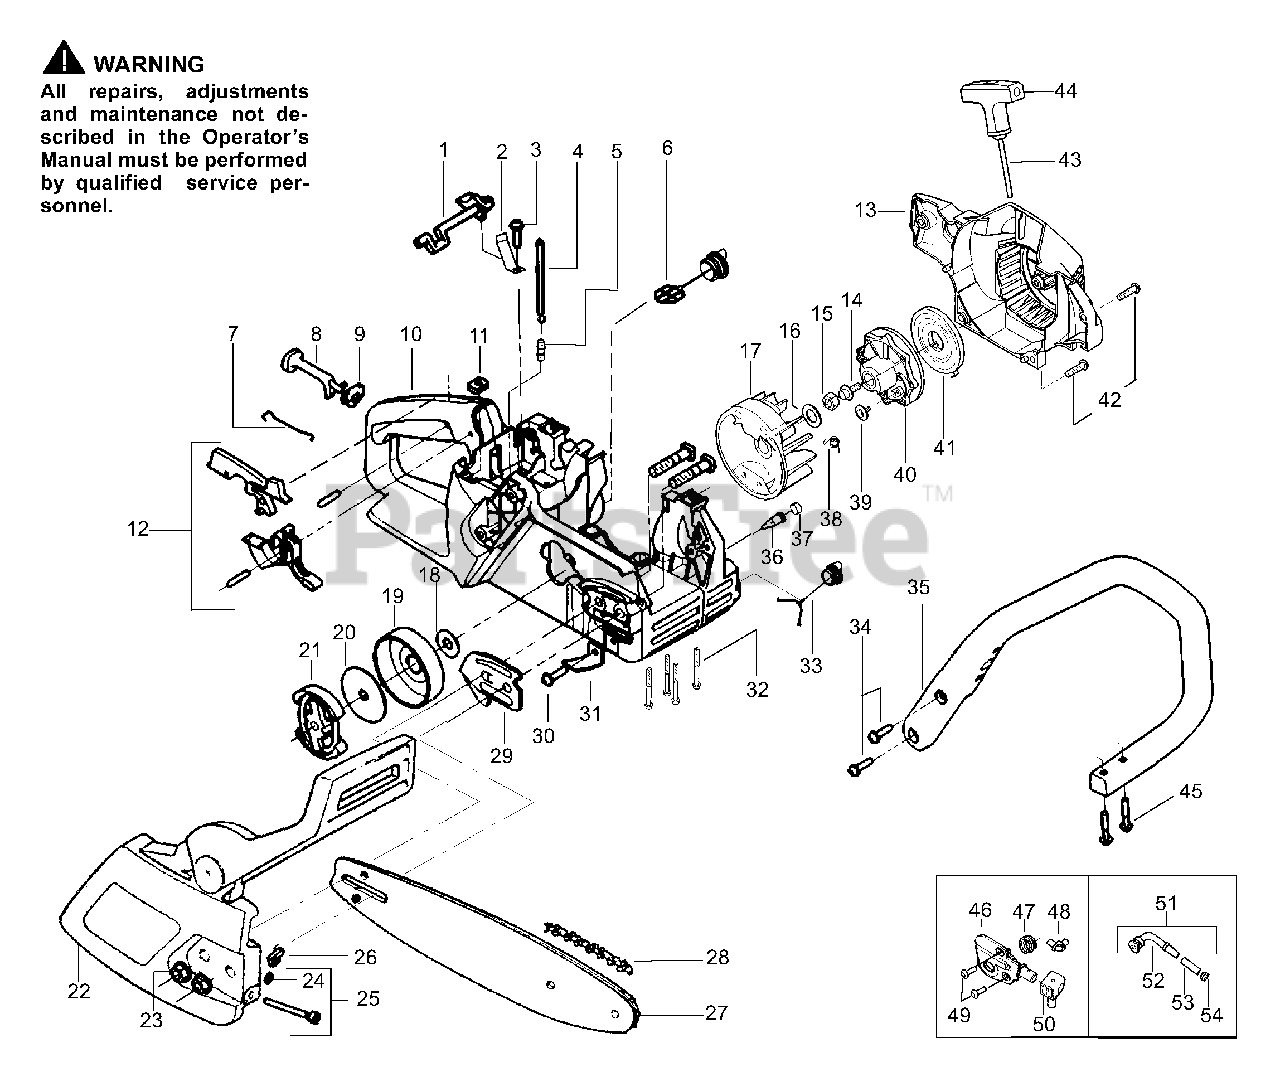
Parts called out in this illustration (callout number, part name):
1	Lever-Switch
2	Spring-Switch
4	Kit-Fuel Line (Large)
6	Assy-Fuel Cap
7	Wire-Throttle
8	Lever-Choke
9	Grommet-Choke Knob
10	Assy-Chassis
11	Nut-Speed
12	Kit-Trigger & Lockout
13	Housing-Fan
15	Nut-Flywheel
16	Washer-Flywheel
17	Assy-Flywheel
18	Washer - Thrust
19	Assy-Drum W/brg.
20	Washer-Clutch
21	Assy. - Clutch
22	Assy-Chain Brake
23	Nut-Bar Mounting
24	Retainer-Bar Adjust
25	Kit-Bar Adjust
26	Pin-Bar Adjust
28	Chain-12"
29	Plate-Bar Mounting
31	Chain Catcher
33	Assy-Oil Cap
35	Handle-Front
36	Valve-Check
37	Plug - Bronze Vent
38	Spring - Starter Dog
40	Pulley-Starter
41	Spring-Starter
43	Kit-Rope
44	Handle-Starter
46	Kit-Oil Pump
47	Gear-Worm Spring
48	Elbow-Oil Pickup
50	Seal Block
51	Assy-Oil-Pickup
52	Pickup-Oiler
53	Filter-Oil
54	Plug-Oil Filter
